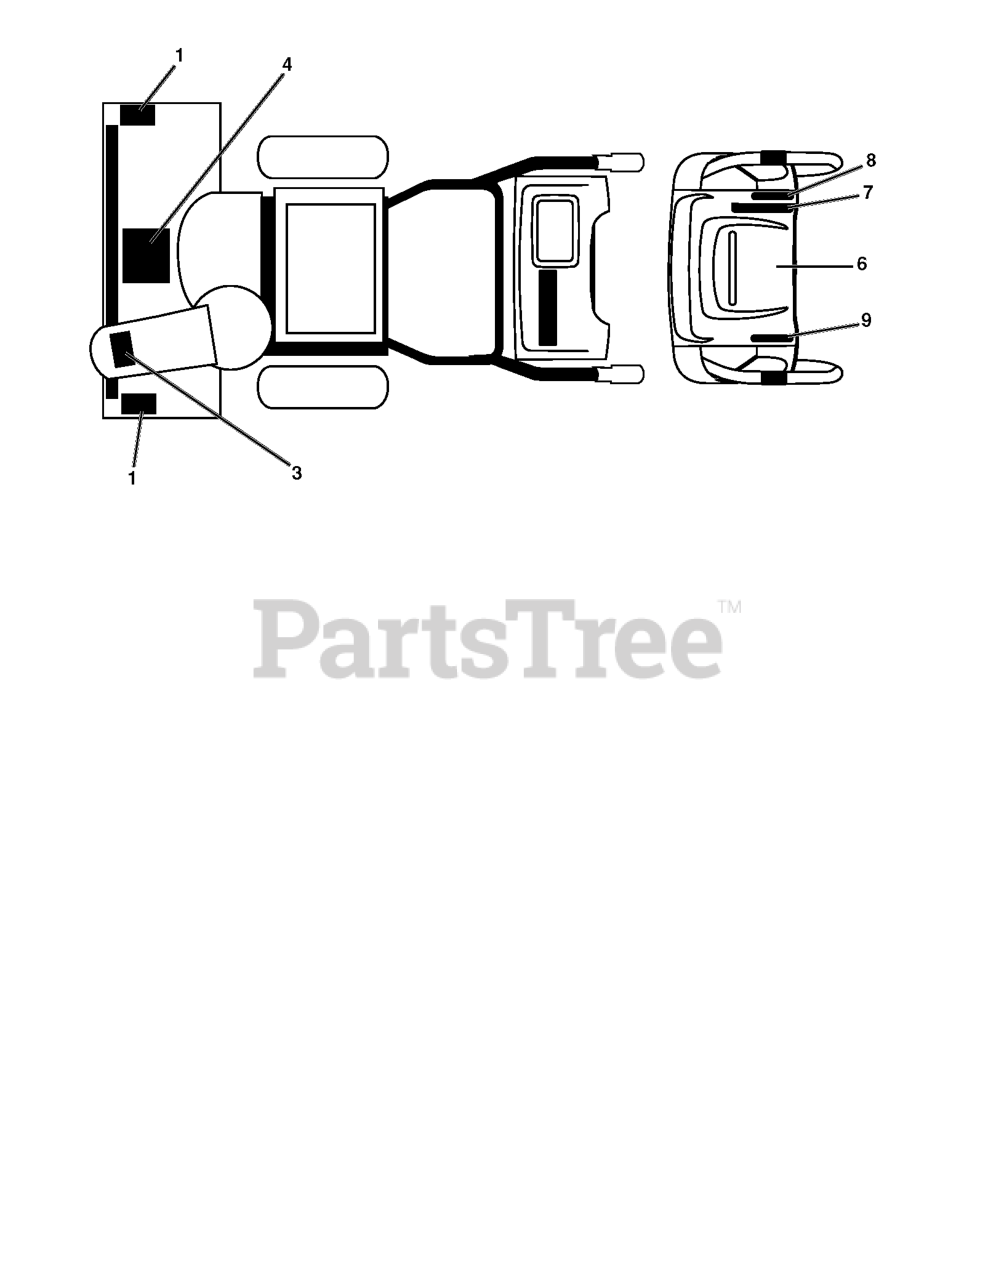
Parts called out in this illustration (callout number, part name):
1	DECAL.SNOWTHR.AUGER
3	DECAL.SNOWTHR.CHUTE.SAFETY
4	DECAL.SNOWTR.READ.OWN.MAN.E/F
6	DECAL, INSTRUCTION
7	DECAL SPEED CONTROL
8	DECAL.AUGER.LEVER.RT.E/F
9	DECAL.TRACT/CLUTCH.LEV.LH.E/F
